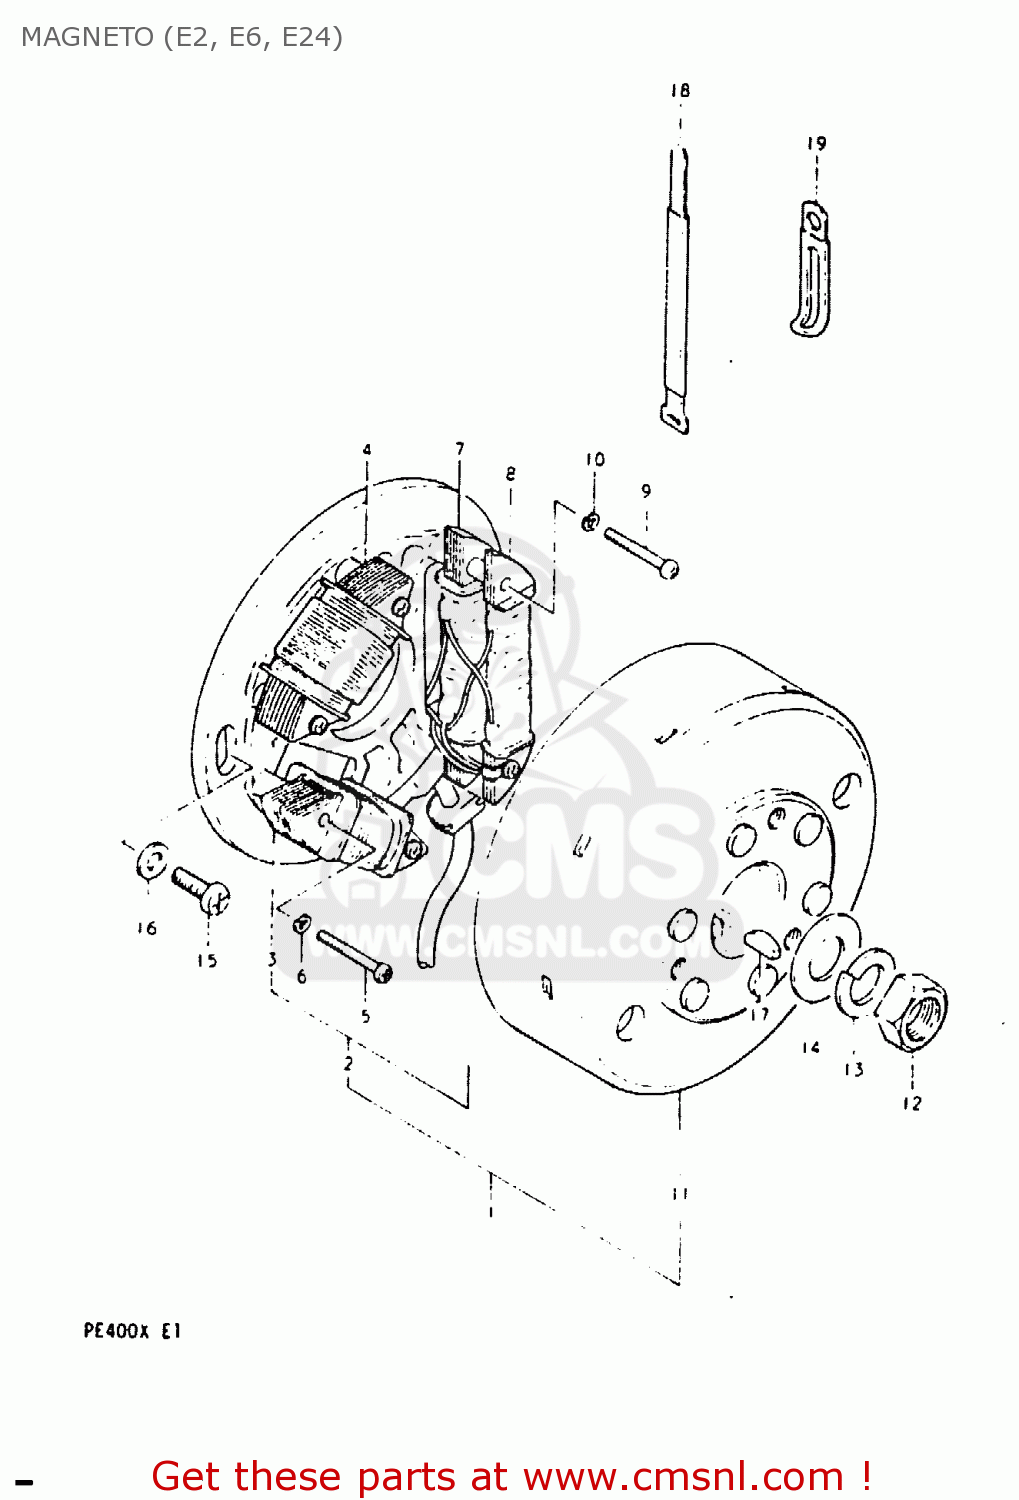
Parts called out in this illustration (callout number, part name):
1	MAGNETO ASSY
2	STATOR ASSY
3	COIL, LIGHTING (A)
4	COIL, LIGHTING (B)
5	SCREW (4X30)
6	LOCK WASHER
7	COIL,PRIMARY
8	COIL,PULSER
9	SCREW
10	LOCK WASHER
11	ROTOR ASSY
12	NUT (10MM)
13	LOCK WASHER
14	WASHER
15	SCREW
16	WASHER
17	KEY 4MM
18	CLAMP L:110
19	CLAMP
